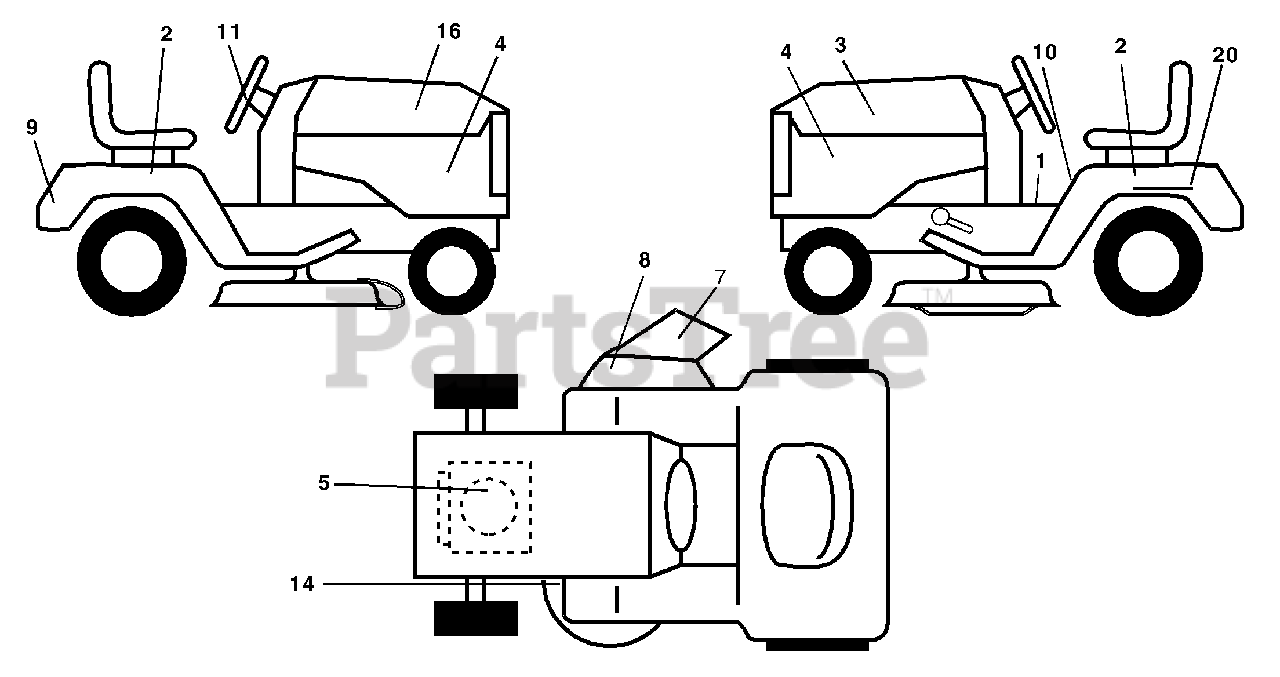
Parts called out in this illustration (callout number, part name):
2	Decal Fender
3	Decal Hood LH
4	Decal Side Panel Logo
5	Decal HP Engine
7	Decal Deck "B" "42"
8	Decal Mower Warn Keep Hand Away
9	Decal Fender Logo
10	Decal Fender Danger E/F
11	Decal Ins Strg Whl
14	Decal V-Belt Schematic
16	Decal Hood Rh
20	Decal Bat Dan/Psn
